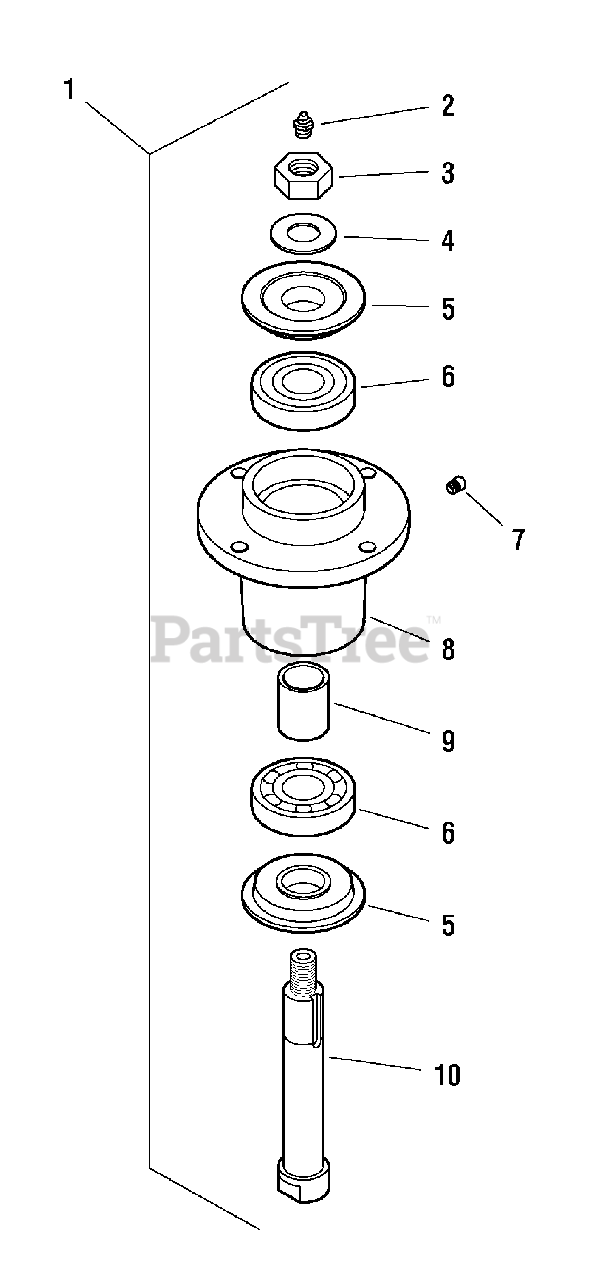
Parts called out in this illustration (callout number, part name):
1	SPINDLE ASSEMBLY, Complete
2	GREASE FITTING
3	NUT, 3/4-16 Hex
4	WASHER, 3/4" Belleville
5	TRASH SHIELD
7	RELIEF VALVE
8	SPINDLE HOUSING
9	SPACER, 1.00 x 1.25 x 1.75
10	SPINDLE SHAFT
